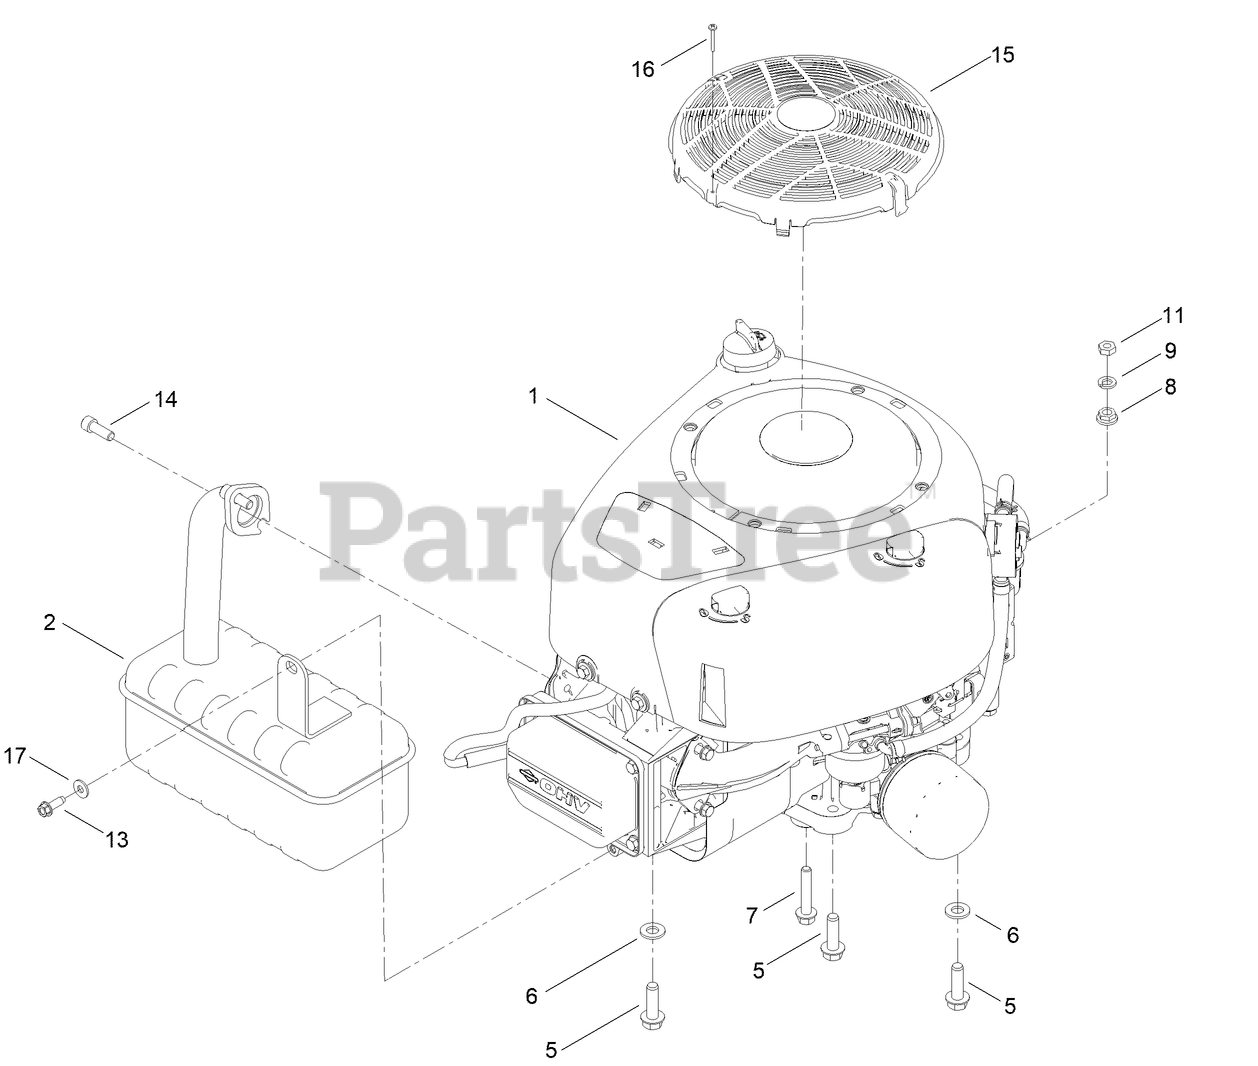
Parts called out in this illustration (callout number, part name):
1	ENGINE-BRIGGS STRATTON PROFESSIONAL
2	MUFFLER
5	SCREW-THD
6	WASHER-FLAT
7	SCREW-HWH
8	NUT-HF
9	WASHER-LOCK
11	NUT-JAM
13	SCREW-HWHTF
14	SCREW-HSH
15	COVER-FAN
16	SCREW-FAN
17	WASHER
